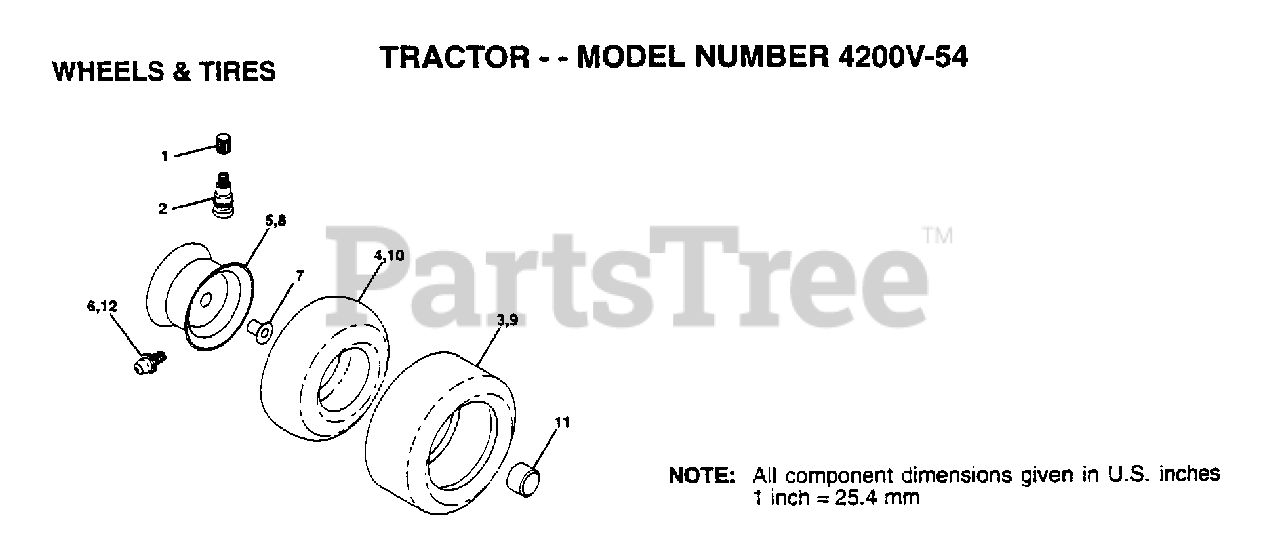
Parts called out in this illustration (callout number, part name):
1	VALVE CAP
2	VALVE STEM LT
4	TUBE.16X6.5/7.5-8
5	RIM.FRONT.
6	ZERK FITTING M
7	"FLANGE, BEARING"
8	"WHEEL,REAR"
10	TUBE.23X8/10-12
11	HUB CAP
12	FITTING LT
